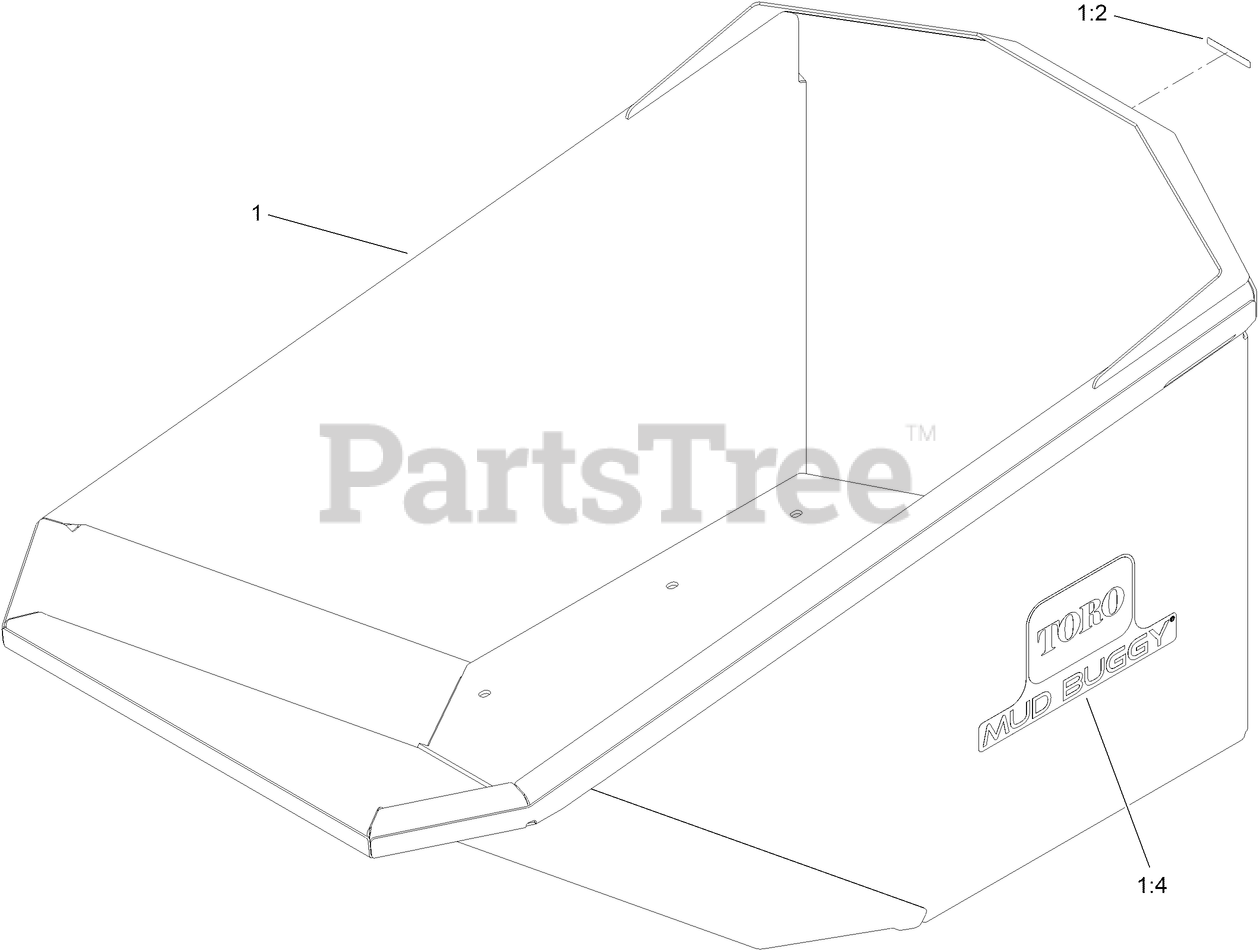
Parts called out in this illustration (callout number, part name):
1	STEEL TUB -
1:2	DECAL-WARNING
1:4	DECAL-MUD BUGGY
